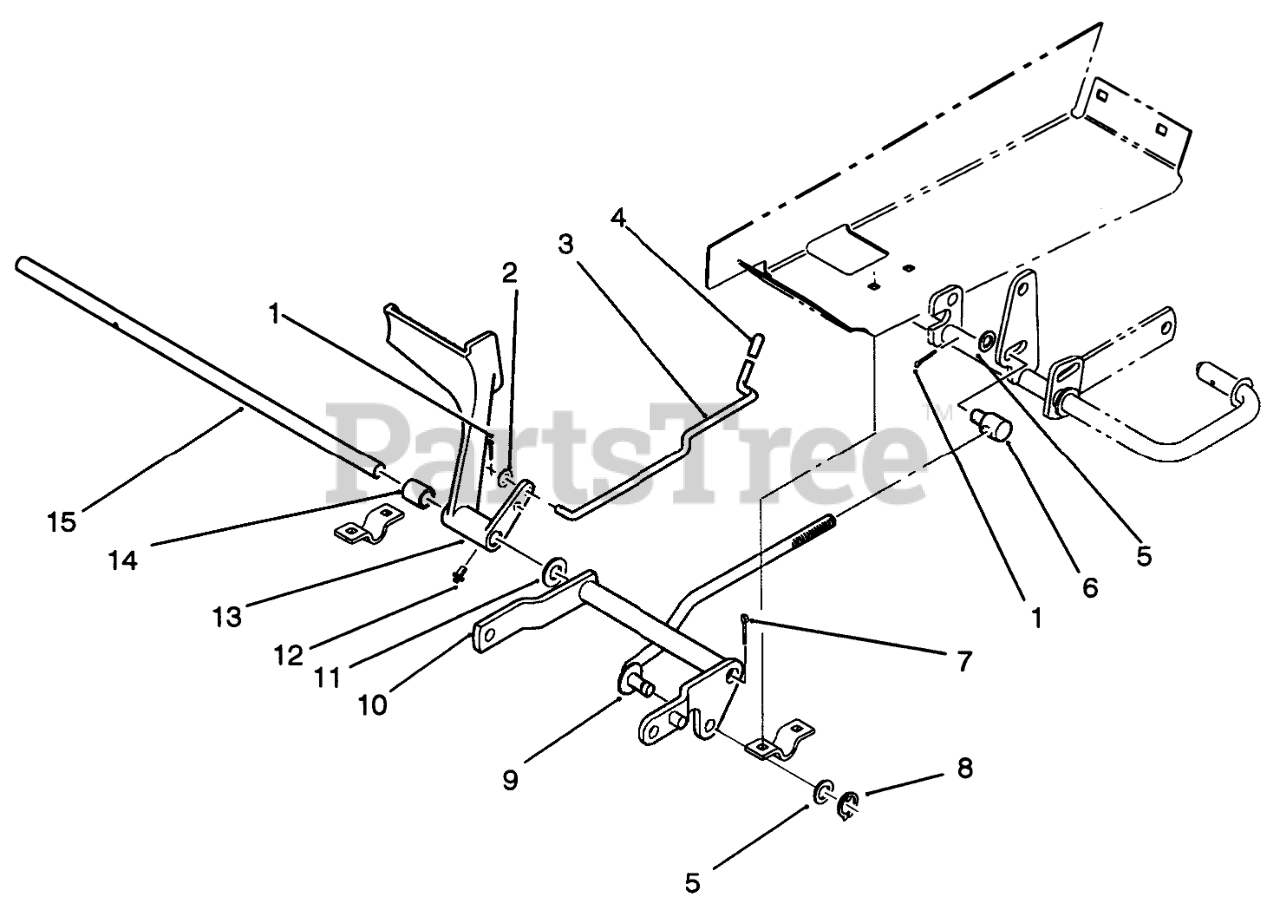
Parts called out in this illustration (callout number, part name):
1	PIN-COTTER
2	NUT-LOCK, NI
3	ROD-BRAKE LOCK
5	WASHER-FLAT
6	ROD-TRUNNION LIFT
7	PIN-COTTER
8	RING-RETAINING, EXTERNAL
10	Arm
11	Washer
12	FITTING-GREASE
13	Pedal-Brake
14	SPACER
15	SHAFT
